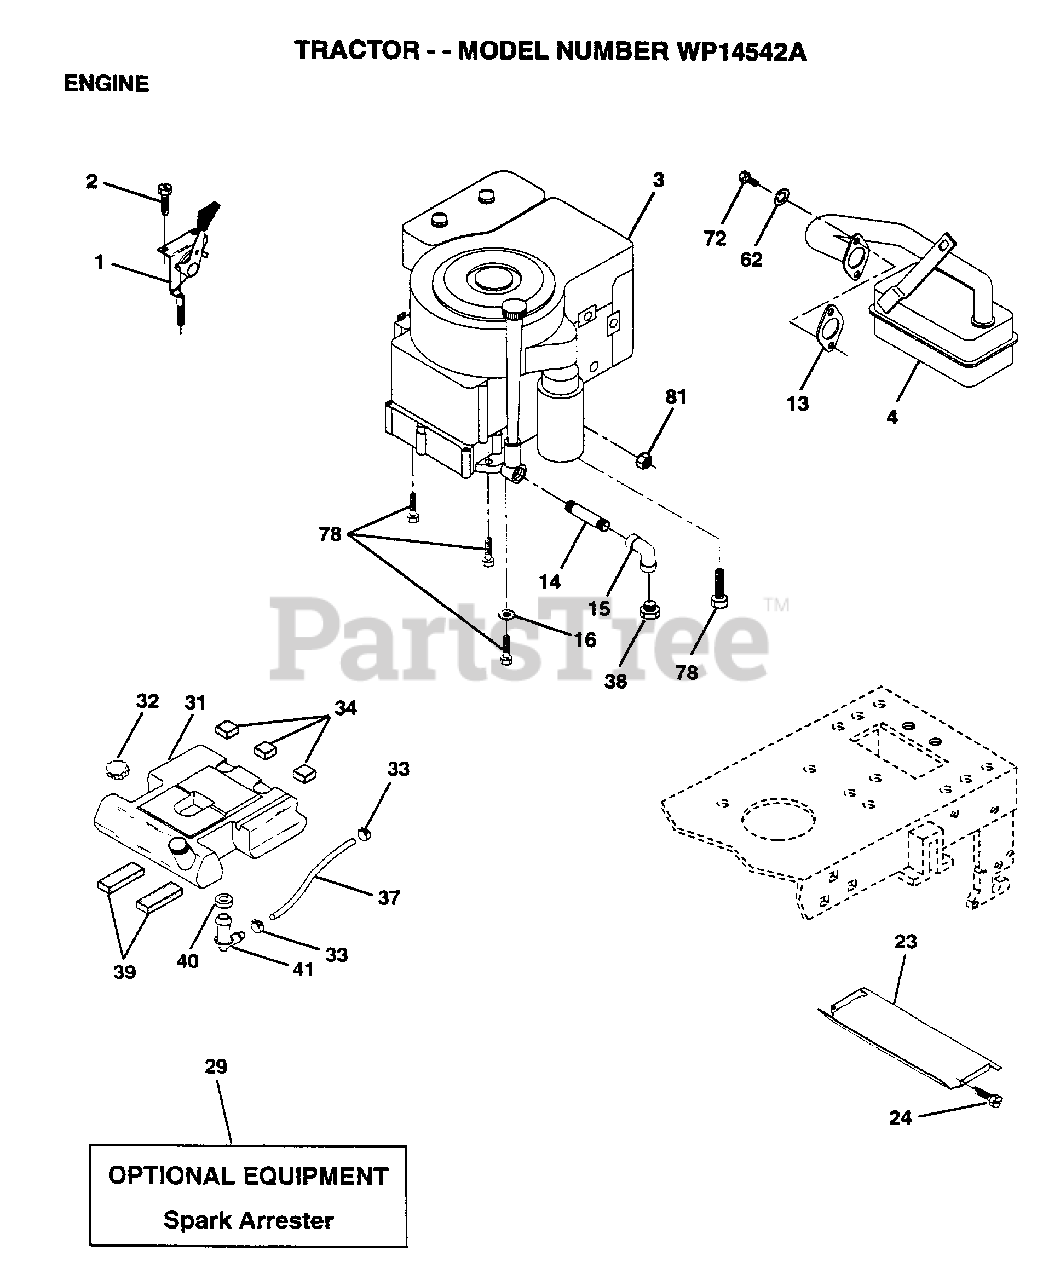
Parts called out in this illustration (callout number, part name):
1	"CONTROL,THROTTLE"
2	SCREW LT
4	MUFFLER
14	PIPE NIPPLE
15	ELBOW
16	LOCKWASHER
23	HEAT SHIELD
24	SCREW
32	CAP ASM FUEL
33	HOSE CLAMP
34	PAD-SPACER LT
37	FUEL LINE T
39	PAD IDLER TI
40	BUSHING OUTLET T
41	STEM.TANK.FUEL
62	LOCKWASHER
72	SCREW
78	SCREW
81	NUT
